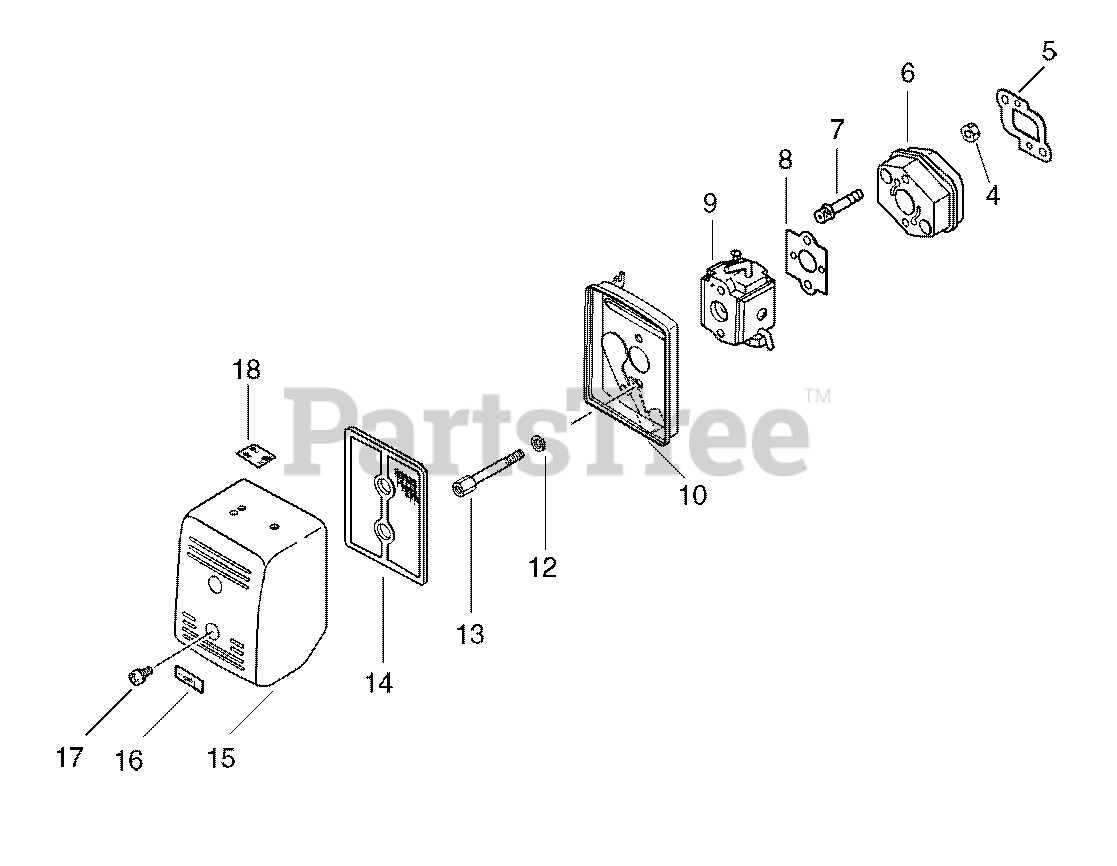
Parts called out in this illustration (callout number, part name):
5	GASKET, INTAKE
6	INSULATOR, INTAKE
7	SCREW - 5X25
8	GASKET, INTAKE
9	CARBURETOR WT-120B
10	CASE, AIR FILTER
12	LOCKWASHER - 5
13	BOLT - 5
14	FILTER, AIR
15	COVER, AIR FILTER
16	LABEL - CHOKE
17	SCREW - 4X8
18	LABEL - ADJUSTING
